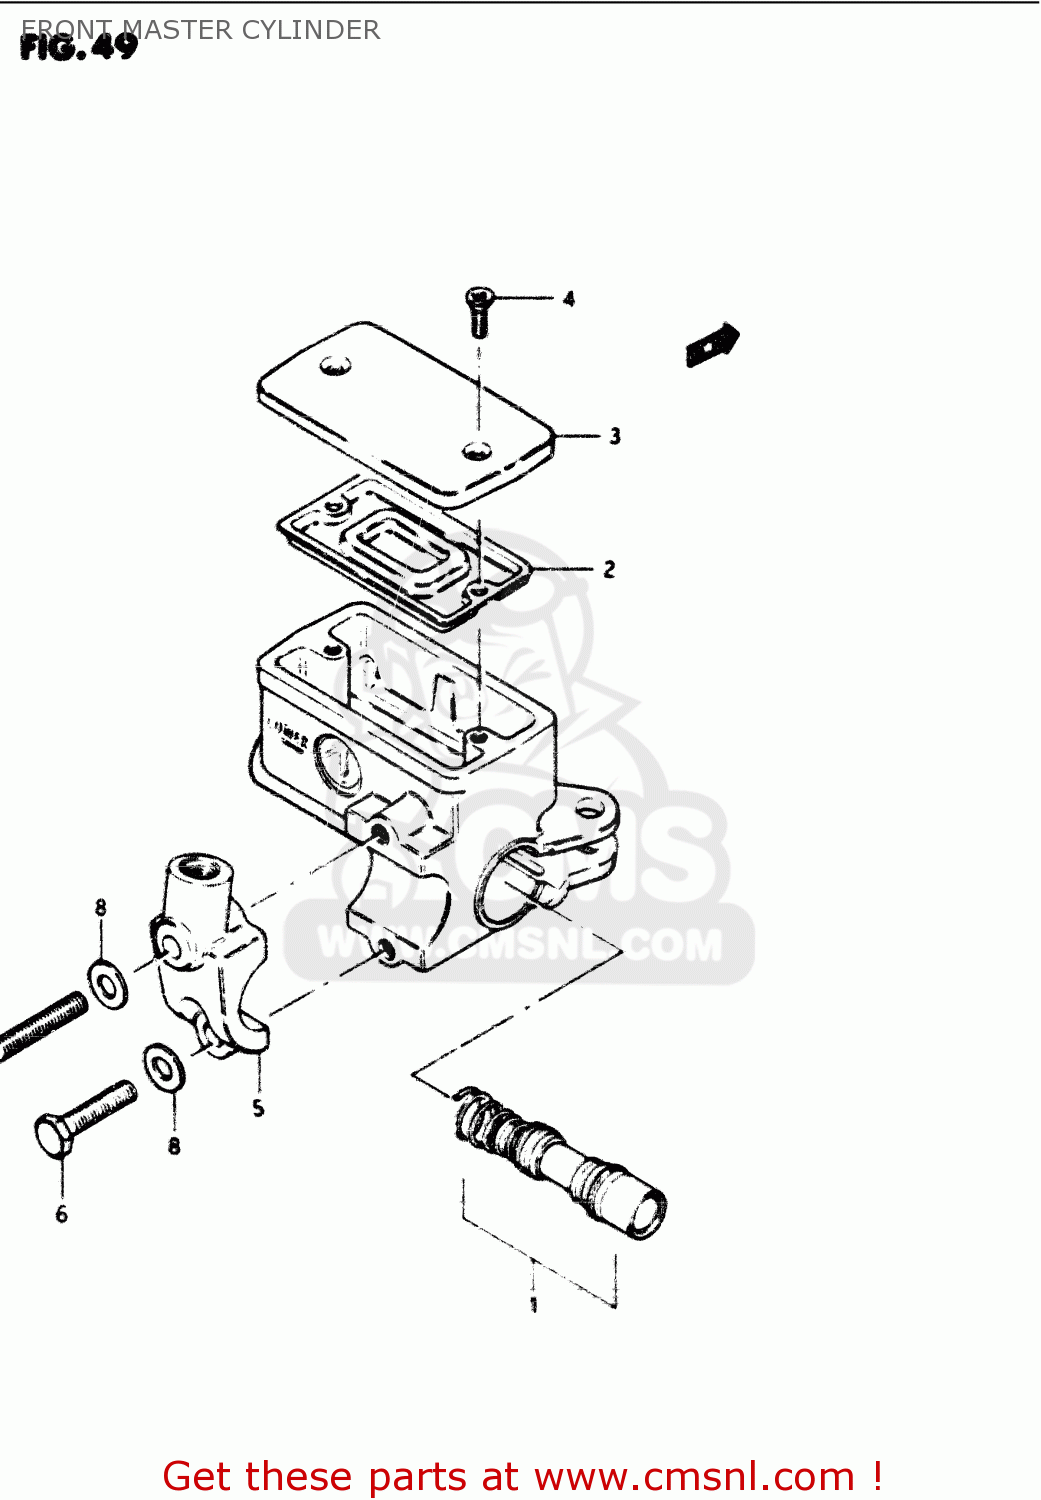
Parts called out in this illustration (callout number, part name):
1	PISTON & CUP SET
2	3-1
3	CAP
4	SCREW
5	HOLDER
6	BOLT
7	BOLT
8	WASHER
